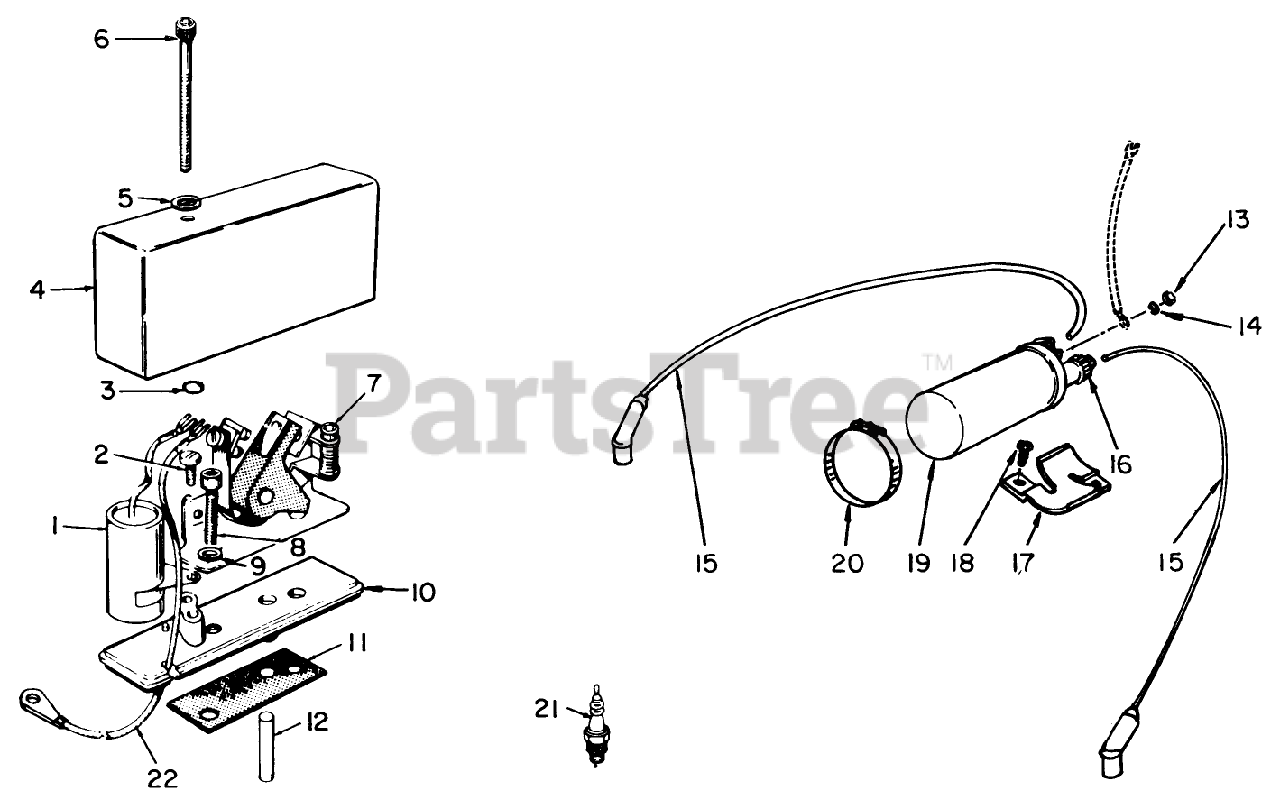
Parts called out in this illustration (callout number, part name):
1	CAPACITOR
6	SCREW-HSH
9	SCREW-HH
11	GASKET
15	CABLE KIT
21	SPARK PLUG
